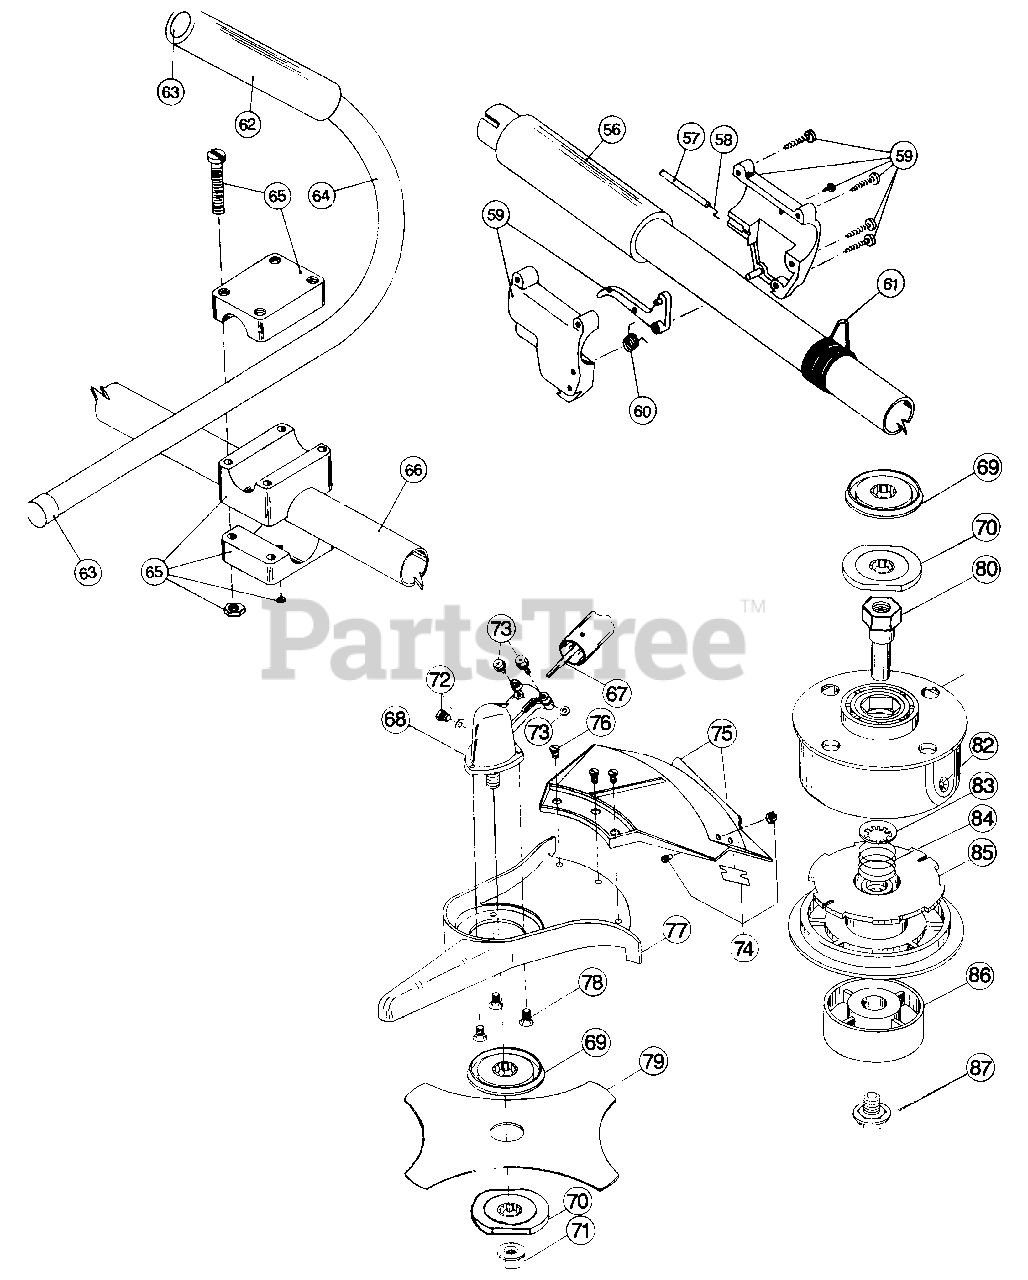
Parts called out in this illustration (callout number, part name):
56	Main handle grip
57	Throttle cable housing assembly
58	Throttle cable
59	Throttle trigger assembly
60	Throttle trigger spring
61	Shoulder strap clamp
62	Grip
63	Tube closure
64	J-handle assembly (includes items 62 & 63)
65	Handle bracket assembly
66	Drive shalt housing assembly
67	Flexible drive shaft
68	Gear box assembly (includes items 69-73)
69	Upper retaining washer
70	Lower retaining washer
71	Lock nut
72	Fill plug assembly
73	Mounting bolt assembly
74	Blade assembly
75	Guard and blade assembly
76	Guard mounting screws
77	Guard
78	Guard mounting screws
79	4-tooth blade
80	Spool shalt
82	Eyelet
83	Retainer (10 pack)
84	Spring
85	Inner reel
86	Bump knob
87	Bump knob bolt
